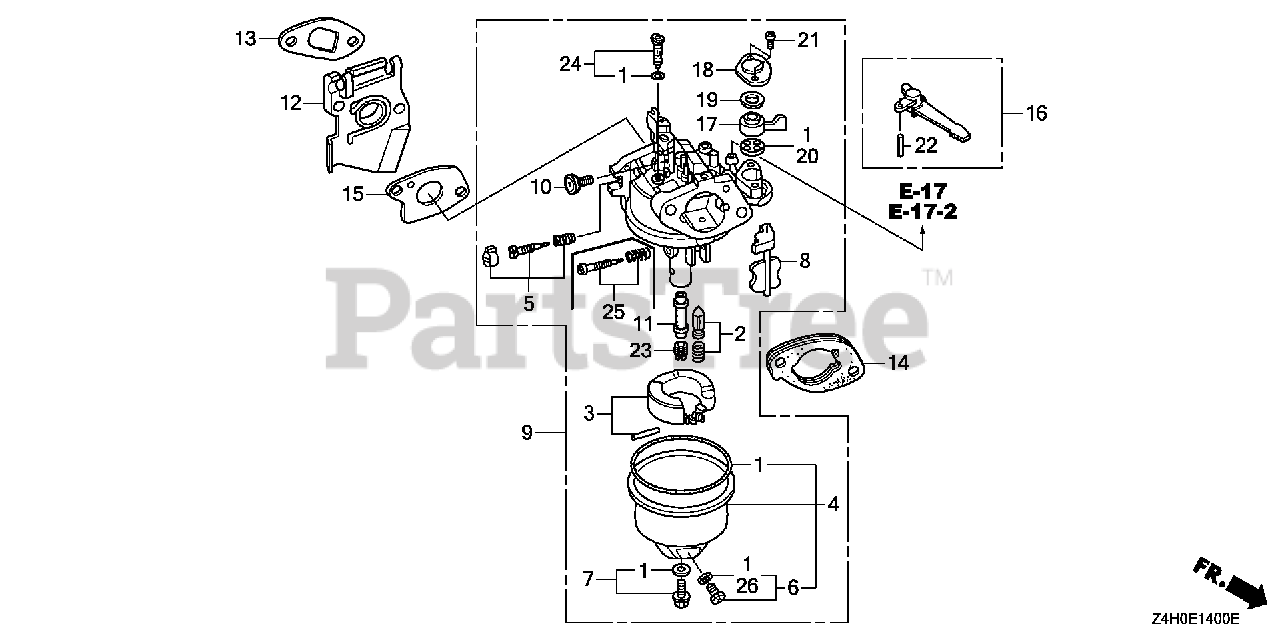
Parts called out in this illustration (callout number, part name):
1	GASKET SET (CARBURETOR NO.)
2	VALVE SET, FLOAT (CARBURETOR NO.) (SEAT NOT INCLUDED)
3	FLOAT SET
4	CHAMBER SET, FLOAT (CARBURETOR NO.)
5	SCREW SET (Honda Code 4219879). (CARBURETOR NO.)
6	SCREW SET, DRAIN (Honda Code 1672187). (CARBURETOR NO.)
7	SCREW SET
8	CHOKE SET
9	CARBURETOR ASSY. (BE61K A)
10	SCREW, THROTTLE STOP
11	NOZZLE, MAIN
12	INSULATOR, CARBURETOR
13	GASKET, INSULATOR
14	SPACER, CARBURETOR
15	GASKET, CARBURETOR
16	LEVER, CHOKE (STD)
17	LEVER, VALVE
18	PLATE, LEVER SETTING (CARBURETOR NO.)
19	SPRING, PETCOCK LEVER (CARBURETOR NO.)
20	GASKET, VALVE
21	SCREW, PAN (3X6)
22	PIN, SPRING (2X12)
23	JET, MAIN (#58) Use from Engine SN BE30B E.
23	JET, MAIN (#60)
23	JET, MAIN (#62)
24	JET SET, PILOT (#35)
26	WASHER, PLAIN (6.2X10.7 DRAIN) (CARBURETOR NO.)
